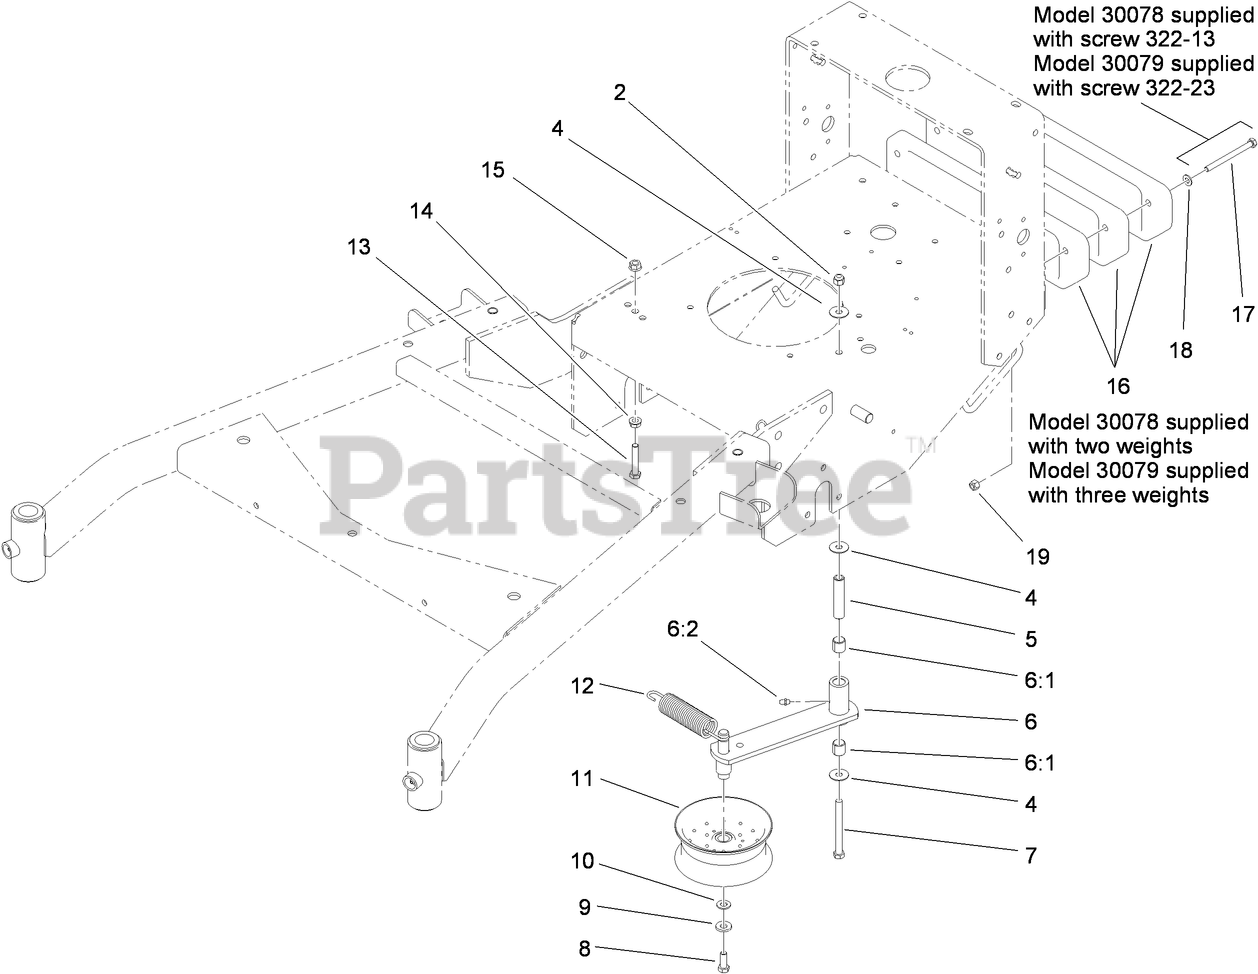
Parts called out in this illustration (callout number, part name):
2	NUT-LOCK, NI
4	WASHER
5	TUBE-IDLER
6	IDLER ARM ASM
6:1	SLEEVE-BEARING
6:2	FITTING-GREASE
7	SCREW-HH
8	SCREW-HH
9	WASHER-BELLEVILLE
10	WASHER-FLAT
11	PULLEY-IDLER
12	SPRING-EXTENSION
13	SCREW-HH
14	NUT-HHF, WHIZ
15	NUT-HF
16	WEIGHT-CAST
17	SCREW-HH
18	WASHER-PLAIN
19	NUT-LOCK, NI
